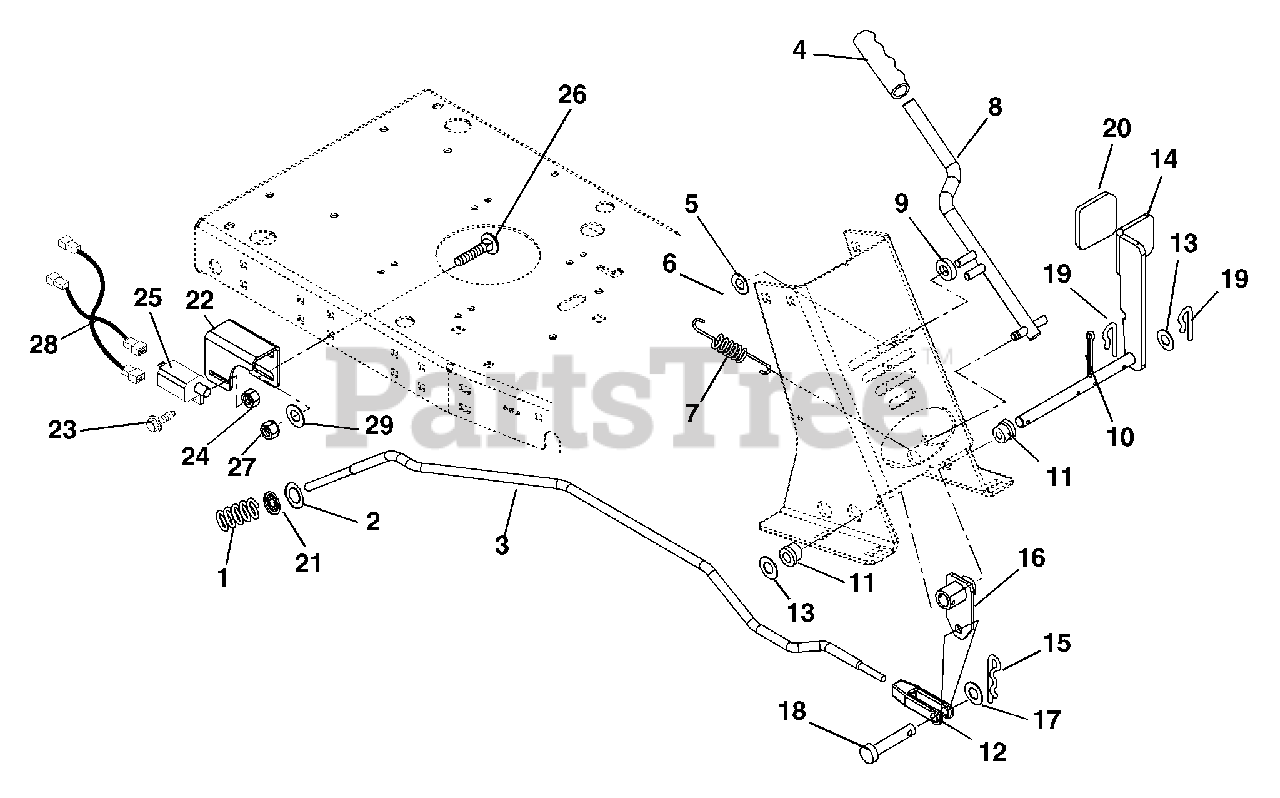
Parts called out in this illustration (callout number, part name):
1	SG-COMP .080X.52X2.90
2	WASHER, FLAT .33/2.125/.098
3	ROD, RER BRAKE
5	@WSHR-FL-STL.38X.875X.083 YWZC
6	NUT-LK-TOP-FLG .38-16 BLKZC
7	SG-TENS .048X.44X2.25 WLD 9
8	HANDLE, PARK BRAKE (WLDMNT)
9	BSHG-FLG .406X.88X.270X.140
10	@PIN-CTR .12X1.00 EXTPRSQCT YZ
11	BSHG-FLG .515X.750X.745X1.00NY
12	YOKE, .312-24 X 2.25
13	WSHR-FL-STL .505X1.00X.062YWZC
14	WLDMT-BRAKE PEDAL
15	PIN-HAIR, ENDRIES #25 YWZC
16	BRAKE ROD ARM & HUB
17	WSHR-FL-STL .328X.87X.179 YWZC
18	PIN-CLEV .312X.822 HDND PL
19	CLIP, SPRING
20	GRIP, PEDAL
21	NUT-PUSH .312
22	BRKT, SWITCH MOUNT
23	@SCR-MCH 10-24X.75 HWH YWZC
24	@NUT-LK-NYL 10-24 W/INSRT YWZC
25	SWITCH- SINGLE POLE N.O.
26	BLT-RDHDSQNK .38-16X1.00 G5BZ
27	@NUT-LK-NYL .38-16 YWZC
28	JUMPER, HARNESS
29	@WSHR-FL-STL.406X.812X.065 YWZ
